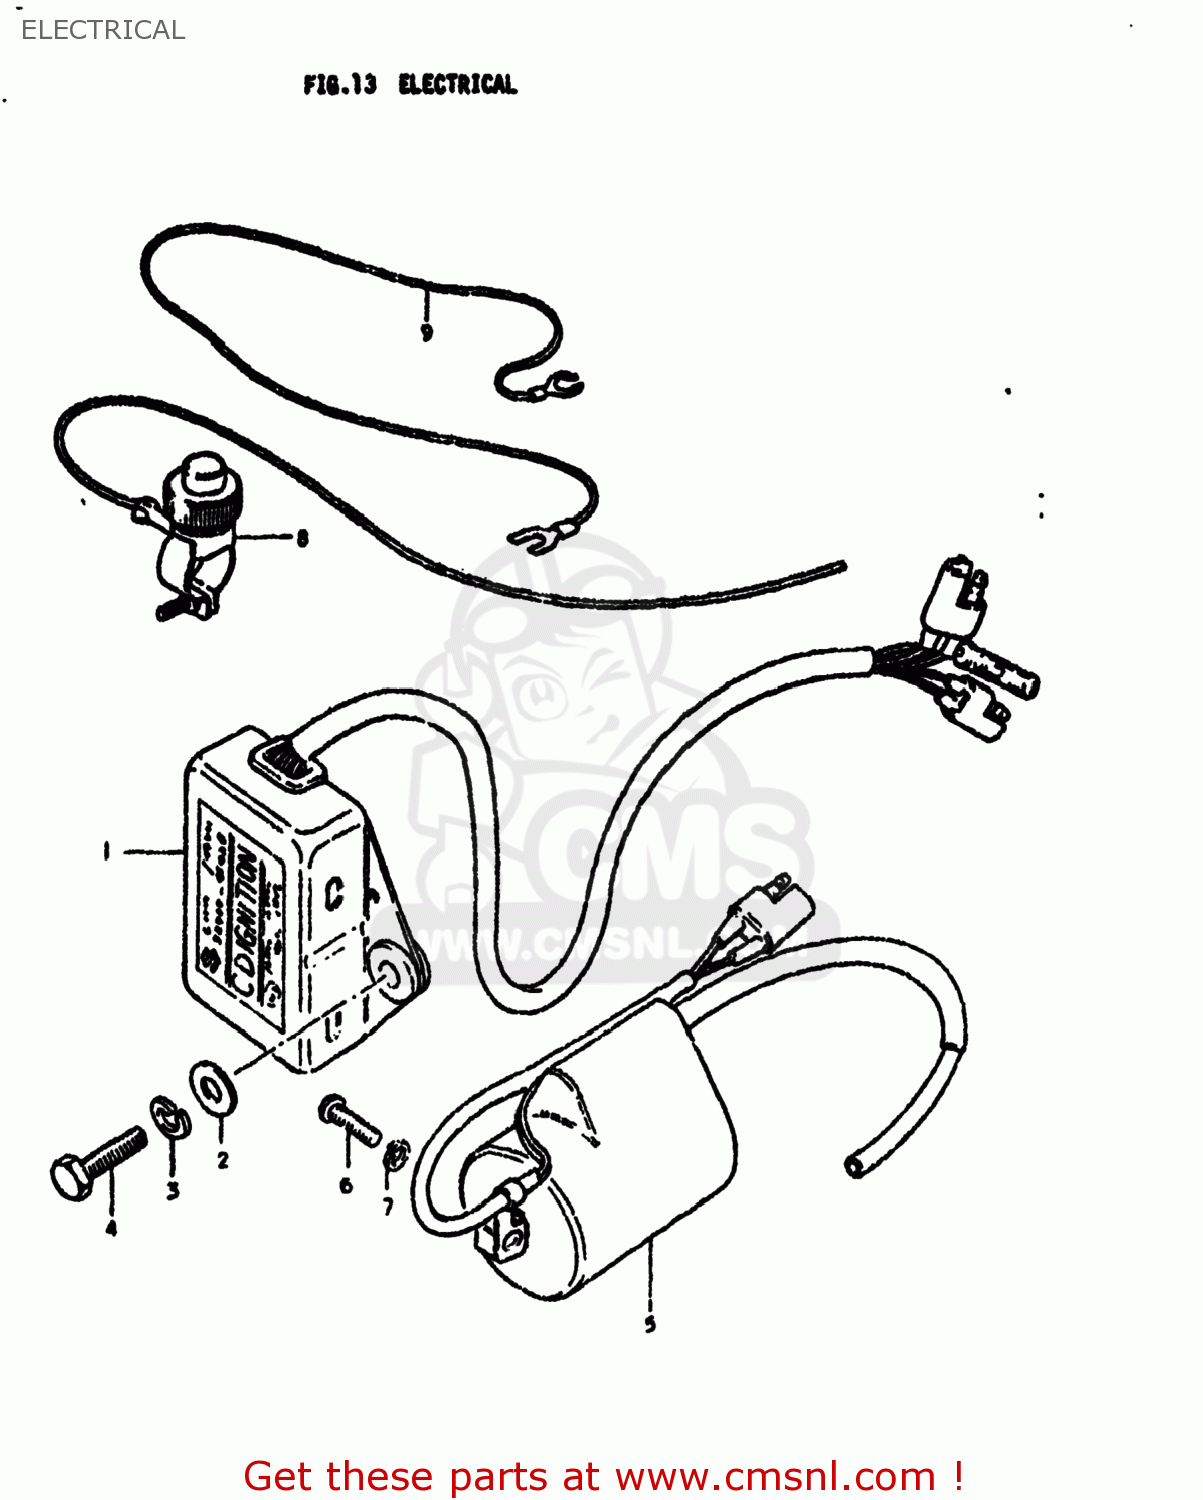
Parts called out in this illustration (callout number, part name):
1	CDI UNIT ASSEMBLY
2	WASHER(6.5X16X1.2)
3	LOCK WASHER
4	BOLT
5	COIL ASSEMBLY,IGNITION
6	SCREW 5X20
7	LOCK WASHER
8	SWITCH ASSEMBLY
9	WIRE,ENGINE STOP EARTH
